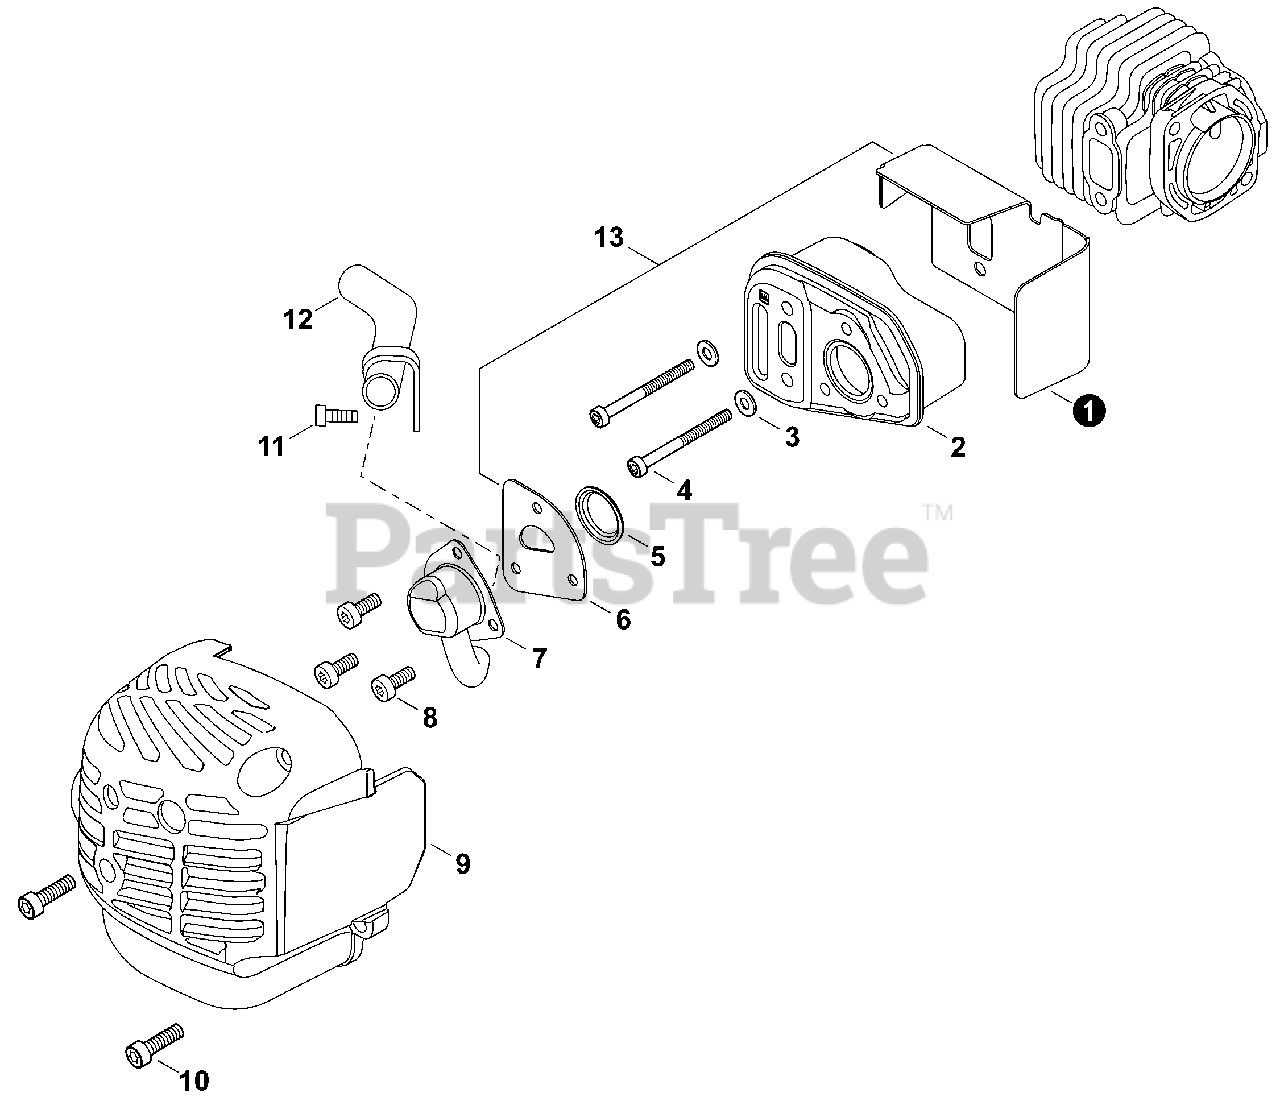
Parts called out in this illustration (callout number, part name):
1	GASKET, EXHAUST
2	MUFFLER
3	WASHER 5.5×12×0.8
4	BOLT, TORX 5×55
5	SCREEN, SPARK ARRESTER
6	GASKET, EXHAUST
7	GUIDE, EXHAUST
8	BOLT, TORX 4×8
9	COVER, MUFFLER
10	BOLT, TORX 5×16
11	BOLT, TORX 5×10
12	OUTLET, EXHAUST
13	GASKET KIT
